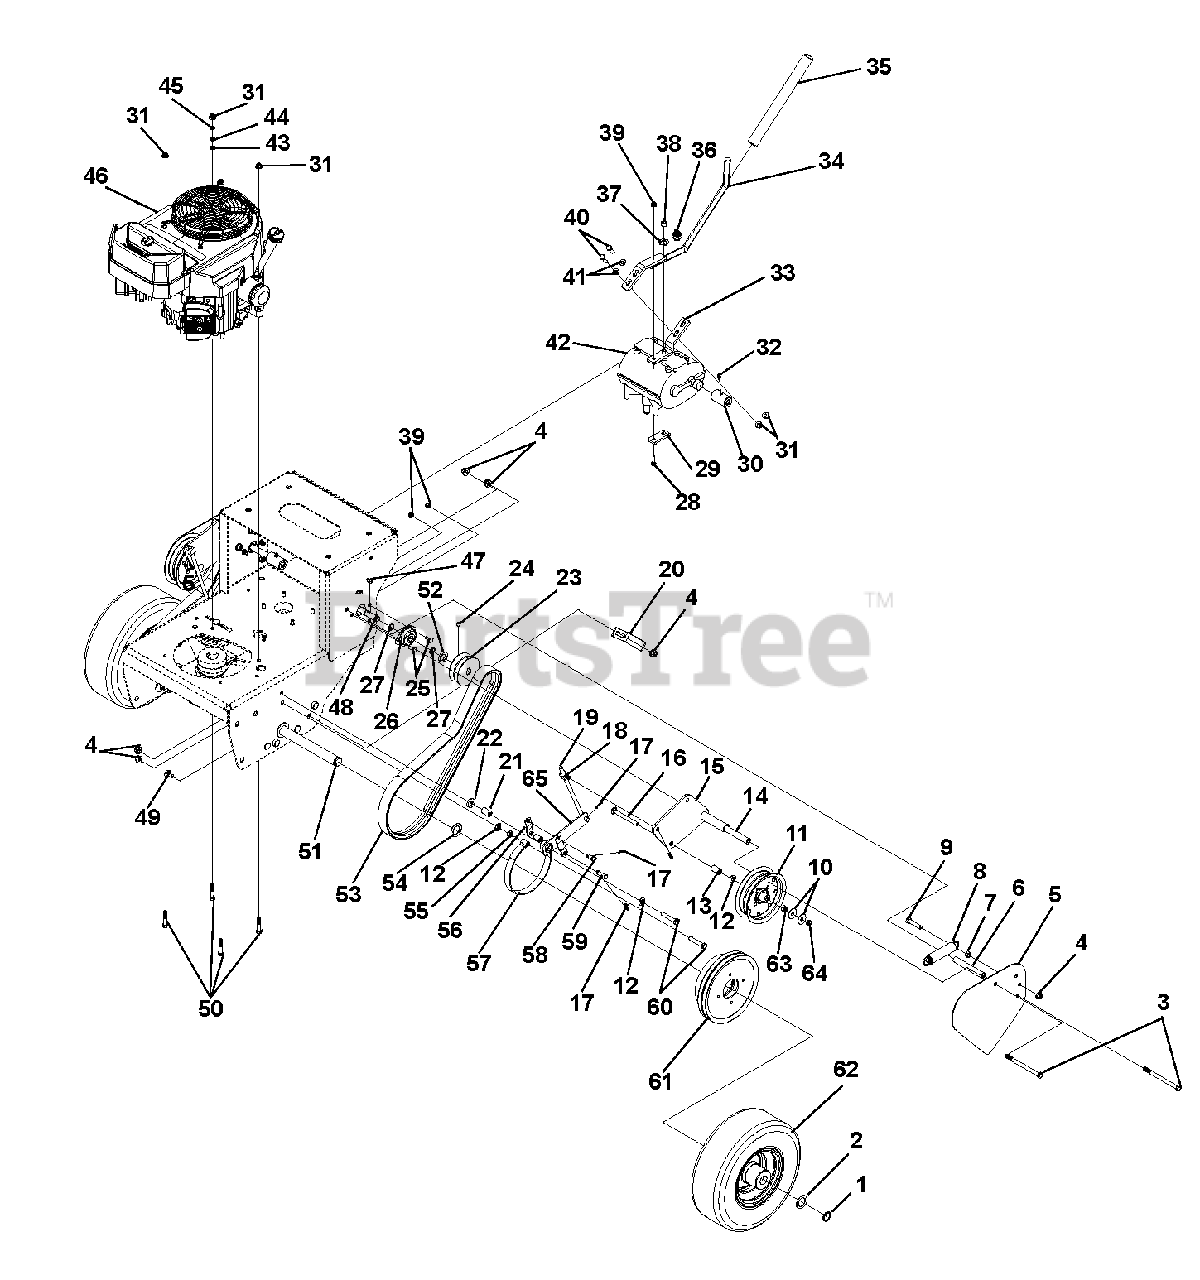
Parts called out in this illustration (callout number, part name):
1	Ring-Retaining-External 1.00 x .078
2	Washer, Flat-Steel 1.010 x 1.505 x .062
3	Bolt, .38-16 x 5.00 Hex 5
4	Nut, .38-16 Nyloc Flange
5	Cover, Traction Belt
6	Bushing,S.385 x .610 x 4.32 Steel
7	Nut, .38-16 Standard Hex Grade 5
8	Spring-Tension .105 x 1.00 x 5.0
9	Bolt, .38-16 x 1.75 Hex 5
10	Washer, Flat Steel .375X1.125X.065
11	Pulley, Flat 5.0 x .38 w/BRG
12	Washer, .406 x .813 x .065 Flat
13	Bushing, Sleeve .375 x .625 x .1.000
14	Bushing, S.385 x .610 x 4.32 Steel
15	Weldment, Wheel Clutching Arm-Left Hand
16	Bolt, Round Head Square Neck .38-16 x 3.5 Grade 5
17	Pin, Hair
18	Swivel, .38-24
19	Rod, Brake Actuating
20	Plate, Belt Finger
21	Bushing, S.391 x .622 x .95 St
22	Washer, Flat Steel .406 x 1.00 x .188
23	Sheave, Drive 3.25 OD x .625 ID
24	Screw, Set .31-18X.38 Socket Head
25	Bolt, Round Head Square Neck .25-20 x .750 Grade 5
26	Bearing, Flange .625 x 1.875 x .797
27	Ring, Retaining-External .579 x .035
28	Bolt, .25-20 x 1.00 Hex 5
29	Plate, Shift
31	Nut, .31-18 Nyloc Flange
32	Fitting, .25-28 STRGT Grease Zerk
33	Bracket, Shift Lever
34	Welment, Shift Lever
35	Grip, Handlebar
36	Switch, Nuetral Start (N.O.)
37	Washer, Locking .375 x .130
38	Nut, Locking-Center .375-24
39	Nut, .25-20 Nyloc Flange
40	Bolt, .3125-18 x 3.25 Hex 5
41	Washer, Flat Steel .344 x .688 x .065
42	Transmission
43	Washer, .313 Medium Spring Lock
44	Nut, Locking-Center Jam .31-18
45	Washer, Locking-EXT .326 x .599 x .031
46	Engine, KAWI FH381V KAI 13HP (410, 411)
47	Key, Woodruff .19 x .75 HRD#9
48	Shaft, Half
49	Bolt, Round Head Square Neck .38-16 x .750 Grade 5
50	Bolt, .3125-18 x 1.75 Hex 5
51	Shaft, Axle
52	Washer, Flat .765 x 1.125 x .187
53	Belt, Gear Drive 49" Elbow COG
54	Washer, Hard-Thrust 1.007 x 1.542 x .062
55	Nut, .38-16 Standard Hex Grade 5
56	Link, Brake Arm
57	Assembly, Brake Band, Pro
58	Pin, CVS .375 x .750 x .516
59	Pin, Clevis .38 x 1.25
60	Bolt, .38-16 x 2.00 Hex 5
61	Assembly, Pulley and Drum
62	Assembly, Wheel And Tire 6 x 3.5 (410)
63	Locknut, .38-16 Center
64	Nut, Locking-Jam-Center .375-16
65	Weldment, Brake Actuating Lever
66	Air Filter
67	Oil Filter
68	Fuel Filter
69	Spark Plug
